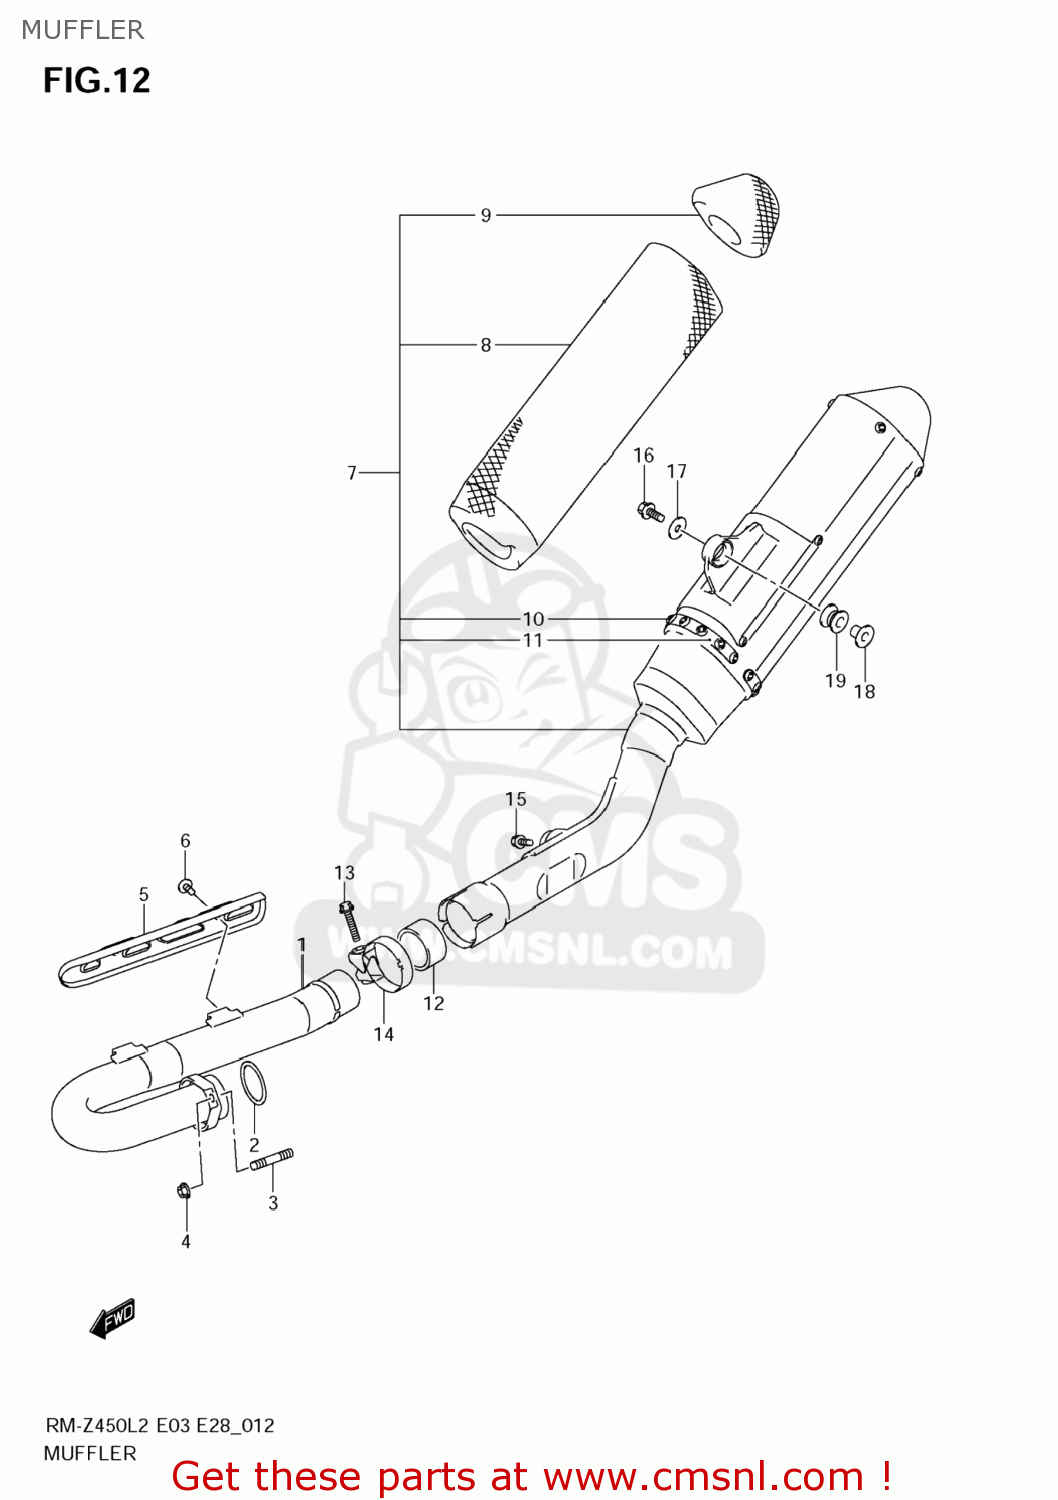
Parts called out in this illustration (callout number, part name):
1	PIPE,EXHAUST
2	GASKET,EXHAUST PIPE (NAS)
3	BOLT,STUD
4	NUT
5	COVER,EXHAUST PIPE
6	BOLT(6X8)
7	BODY,MUFFLER
8	SILENCER,MUFFLER
9	GLASS WOOL,MUF TAIL
10	RIVET,MUFFLER
11	BAND,MUFFLER
12	CONNECTOR,MUFFLER
13	BOLT(8X35)
14	CLAMP,CONNECTOR
15	BOLT(8X20)
16	BOLT(8X35)
17	WASHER(8.5X26X1.6)
18	SPACER(8.6X12X18.5)
19	CUSHION
